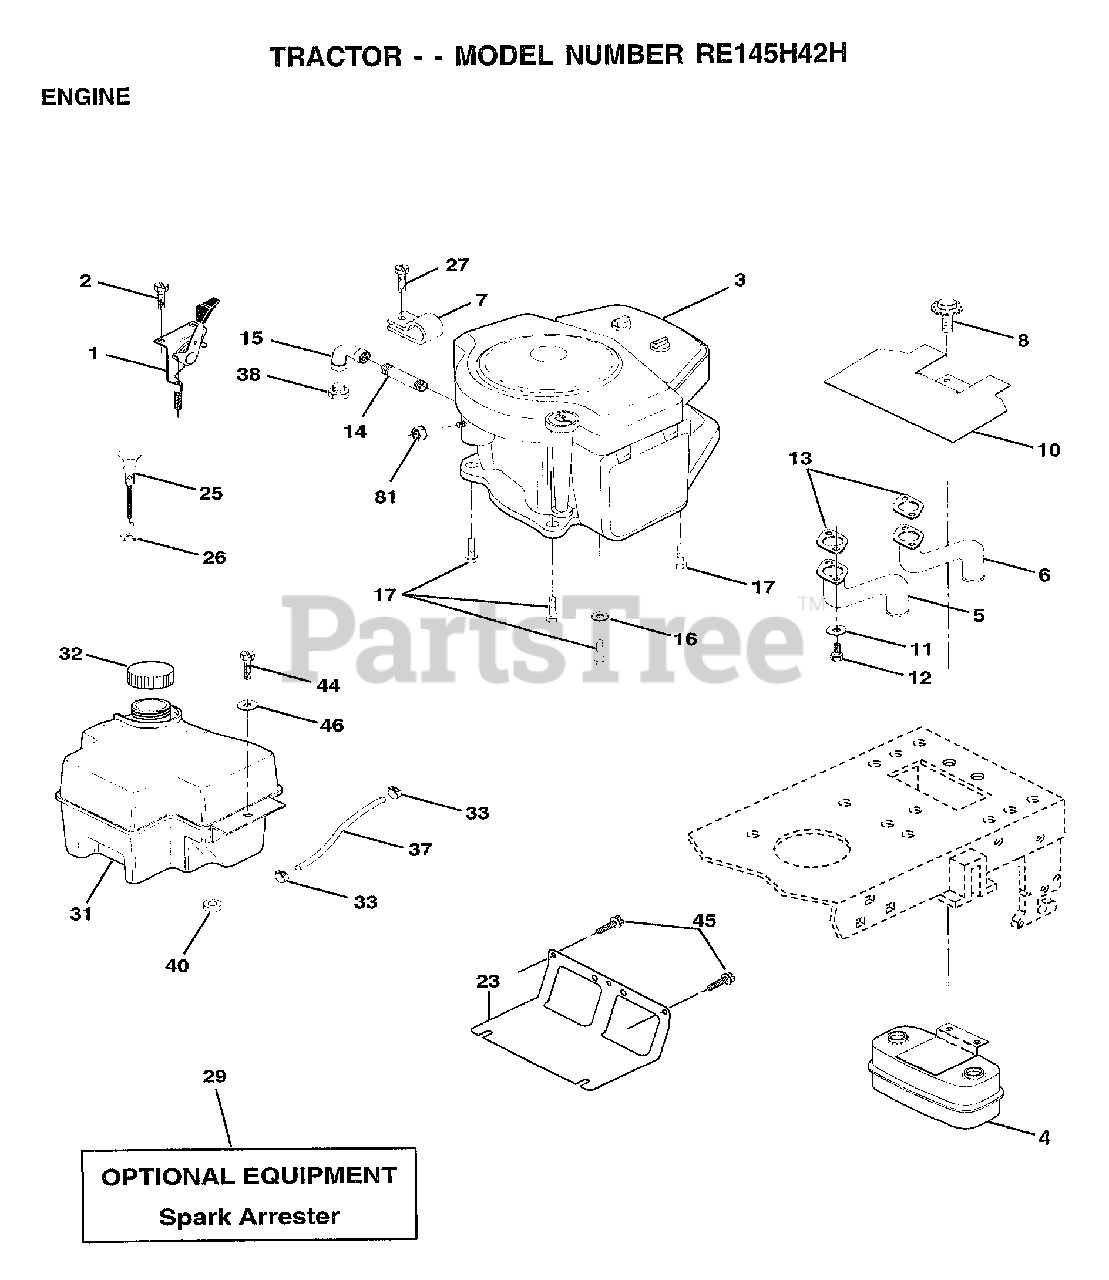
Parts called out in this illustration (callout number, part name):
1	CONTROL THRT 35.5
2	SCREW LT
4	MUFFLER.TW.LOTONE
5	EXHAUST.B&S.18.LH
6	EXHAUST.B&S.18.RH
7	CLAMP.TUBE.DBL.EN
8	BOLT.5/16-18.UNC
10	SHIELD.HEAT.
11	LOCKWASHER
13	GASKET MUFFLER
14	PIPE NIPPLE LT
15	ELBOW
16	LOCKWASHER
17	SCREW LT
23	SHIELD BROWNING
25	CONTROL.CHOKE.37
26	"NUT,KEPS 3/8-24IM"
27	"SCREW-TT,10-32 FL"
31	TANK.FUEL.FRONT.
32	CAP ASM FUEL
33	HOSE CLAMP
37	LINE FUEL
44	SCREW
45	SCREW
46	WASHER
81	NUT
